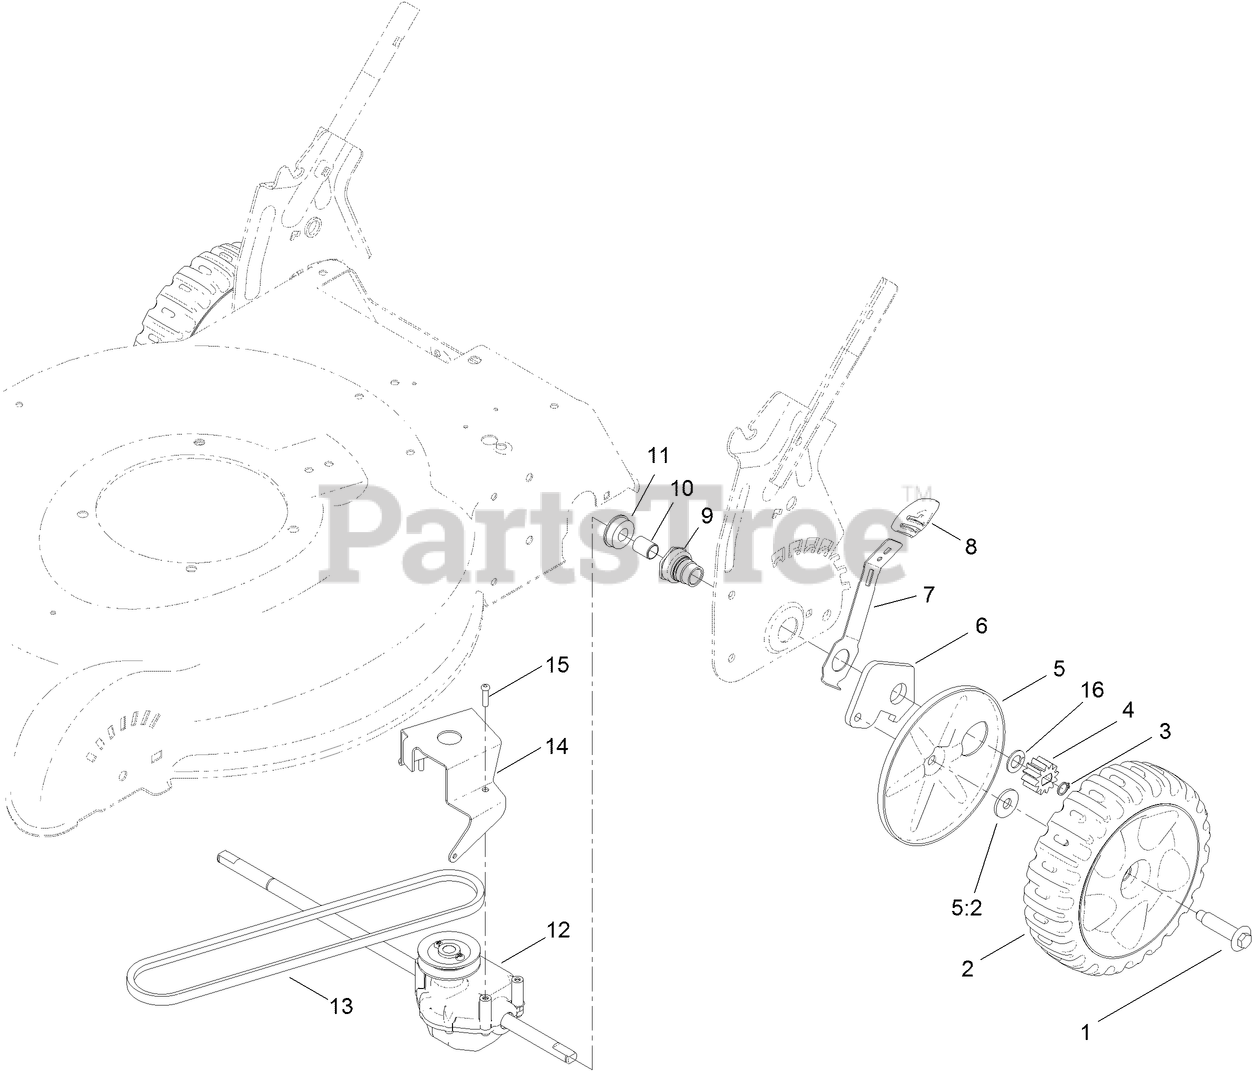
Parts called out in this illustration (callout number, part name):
1	BOLT-SHOULDER
2	8 INCH WHEEL GEAR ASM
3	RING-RETAINING
4	GEAR-PINION
5:2	WASHER-STEPPED
6	ARM-PIVOT, REAR
7	ARM-SPRING
8	KNOB-LEVER, HOC
9	RETAINER-BUSHING, HOC
10	BUSHING-SLEEVE
11	BEARING-BALL
14	BRACKET-TRANSMISSION
15	SCREW-PAN HEAD, T20
16	WASHER-THRUST
